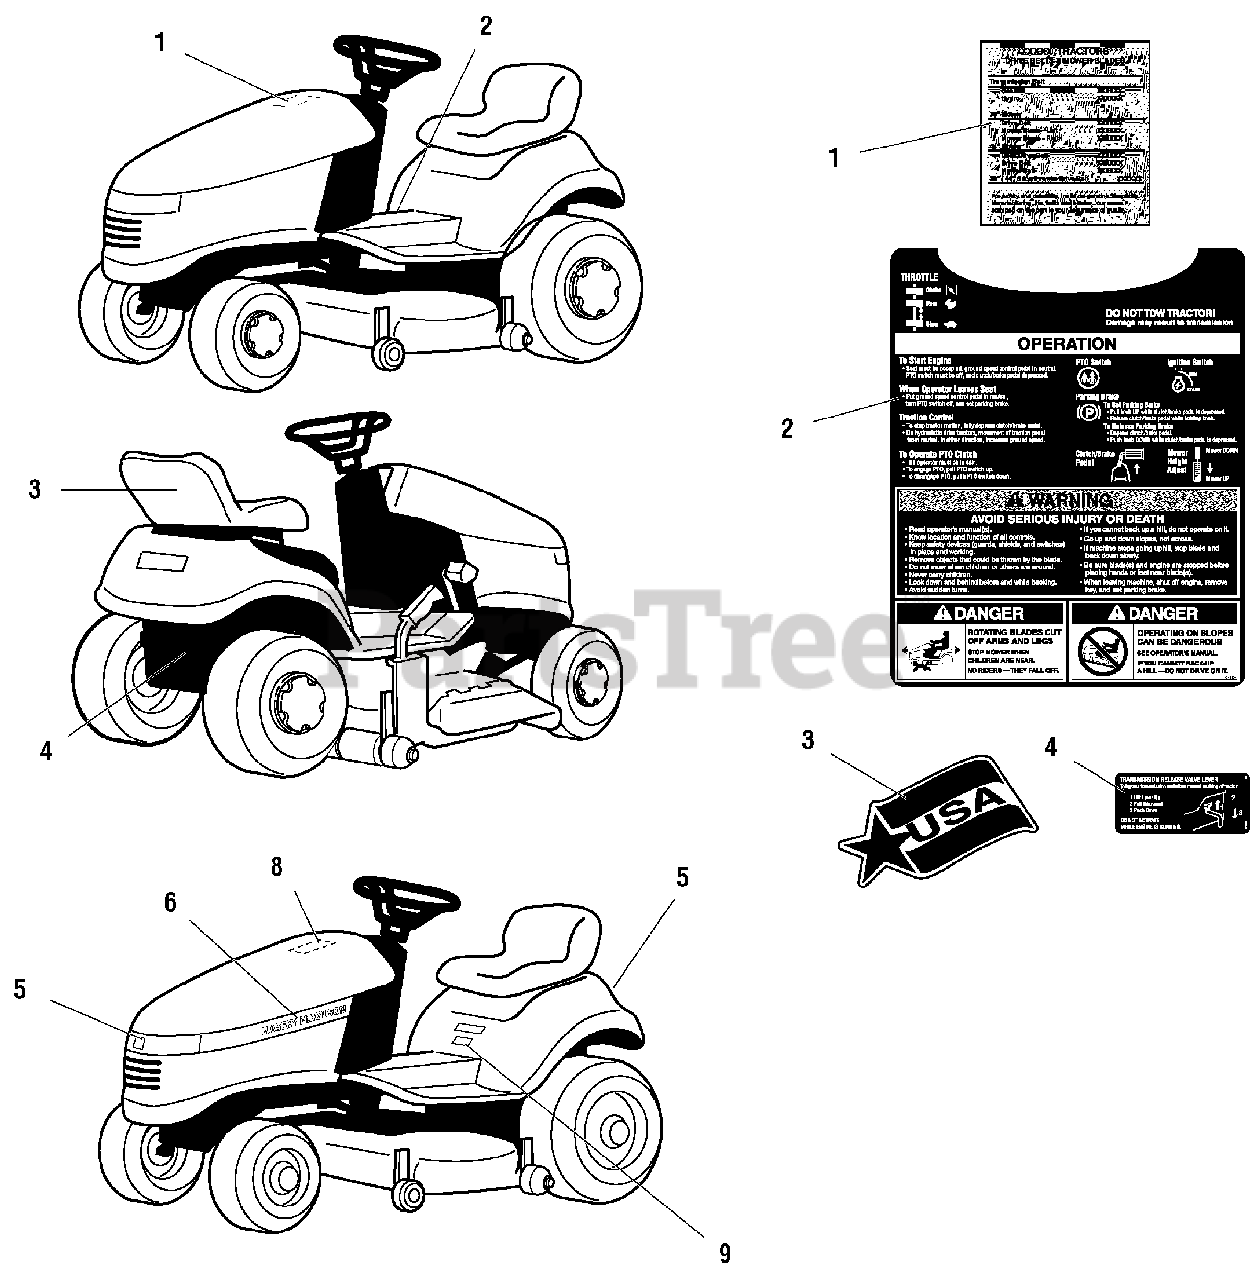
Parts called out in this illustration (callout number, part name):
1	DECAL, Drive Belts / Mower Blades (Under Hood)
2	DECAL, Operating Instructions
3	DECAL, USA Logo
4	DECAL, Transmission Release Valve
5	DECAL, Massey Ferguson Logo
6	DECAL, 2517H, L.H.
7	DECAL, 2517H, R.H.
8	DECAL, Touch Up Paint
9	DECAL, 17HP
10	DECAL, Patent
